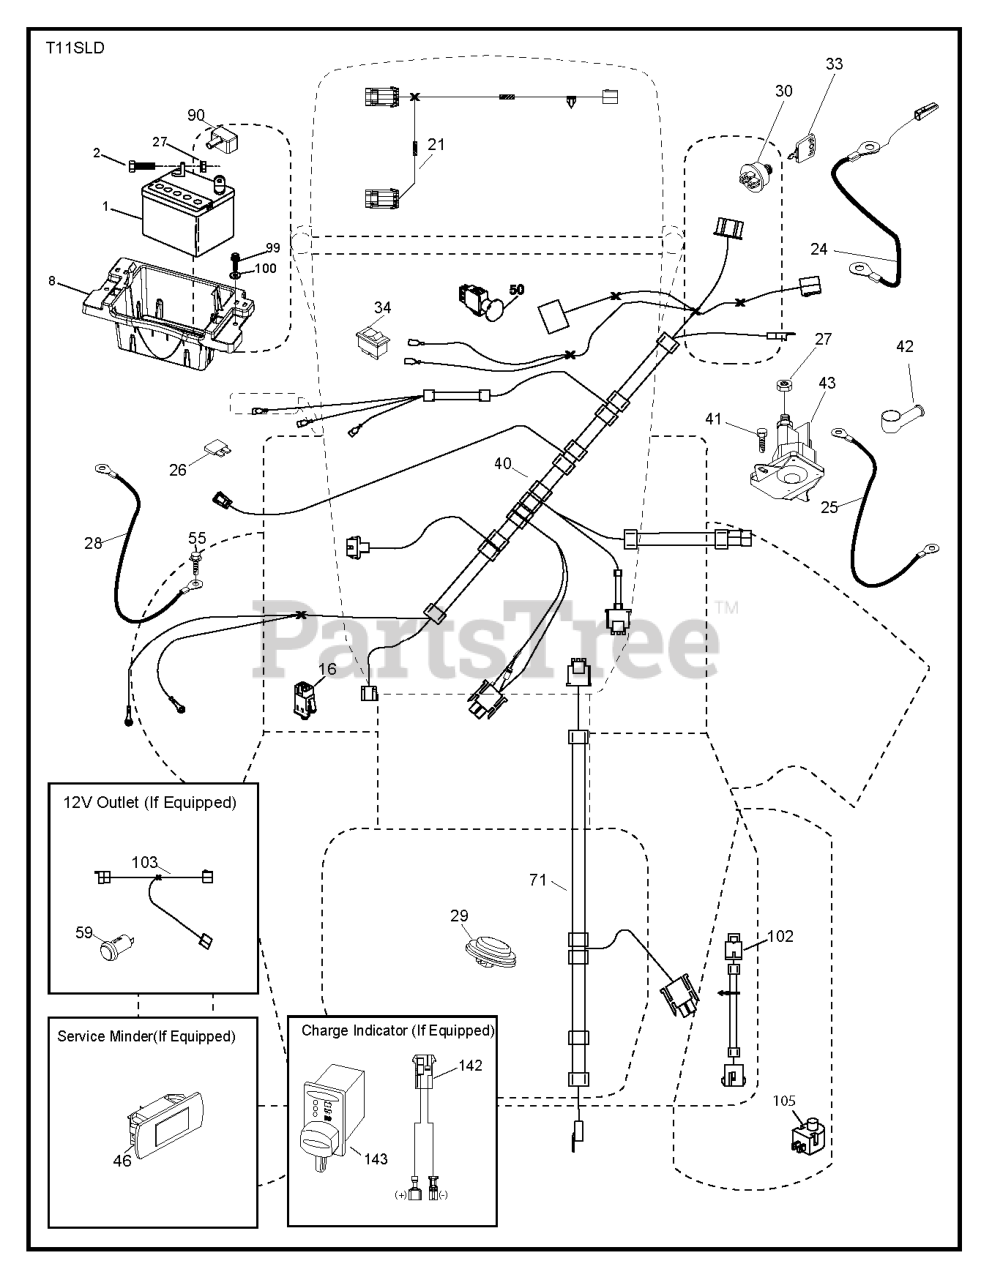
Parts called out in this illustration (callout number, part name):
1	Battery 12 Volt 25 Amp
2	BOLT.HEX.1/4.X.3/4.DICHROMATE
8	TRAY.BATTERY BOX.FRONT
16	SWITCH INTERLOOK PUSH-IN
21	HARNESS LIGHT ASSY TRACTOR,
24	CABLE.FRBATT.W/WIRE.8GA.8
25	CABLE.BATT.RED.8GA.17
26	FUSE 20AMP
27	NUT
28	CABLE.GROUND.21"BLK.8GA.90T
29	SWITCH.SEAT.DELTA.OPC.
30	SWITCH.IGN.DELTA.W.LGH.ROS
33	KEY.CHAIN.BLISTER.PACK.GEN.USA
40	HARNESS HARNESS..DASH.ING.ELEC
41	SCREW
42	TERMINAL COVER
43	SOLENOID.STARTER.BRASS.PLUNGER
46	GUAGE.SRVCMNDR.HRMTR.
50	SWITCH.PTO.8TERMINAL.STD.BLK
55	SCREW 5/16"
71	HARNESS-CHASSIS SUB
90	COVER.TERMINAL.BATTERY
99	SCREW HEXWSHR 1/4-20X3/4
102	HARNESS PIGTAIL PCH TEX ROS
105	REVERSE SWITCH
